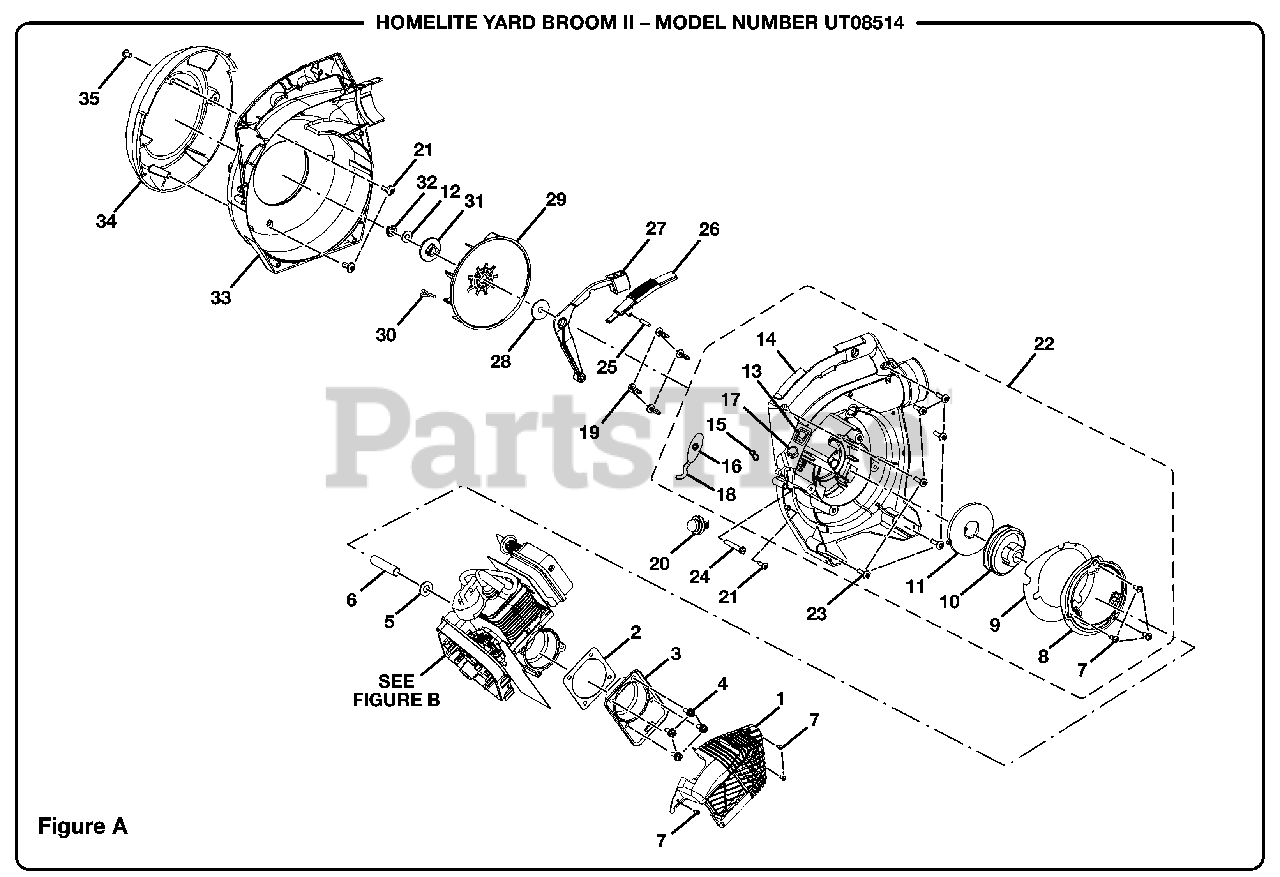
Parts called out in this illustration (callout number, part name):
1	Blower Shroud
2	Crankcase Gasket
3	Crankcase Cover
4	Screw (10-24 X 9/16 in Pan Hd.)
5	Flat Washer
6	Fan Spacer
7	Screw (#8 X 1/2 in Pan Hd.)
8	Baffle
9	Baffle Gasket
10	Pully
11	Spring & Container
13	Switch
14	Inner Volute Housing
15	Bushing - Starter Rope
16	Starter Grip
17	Bushing
18	Starter Rope
19	Screw (10-24 X 3/4 in Truss Hd.)
20	Primer Bulb
21	Screw (10-14 X 1/2 in Torx Truss Hd.)
22	Inner Housing & Starter Assembly
23	Screw (10-14 X 3/4 in Torx Truss Hd.)
24	Screw (10 X 1-5/8 in Hex Hd.)
28	Flat Washer
29	Fan
30	Wire Loop
31	Fan Adaptor
32	Lock Nut (3/8-24)
33	Outer Volute
35	Screw (1/4-20 X 3/4)
